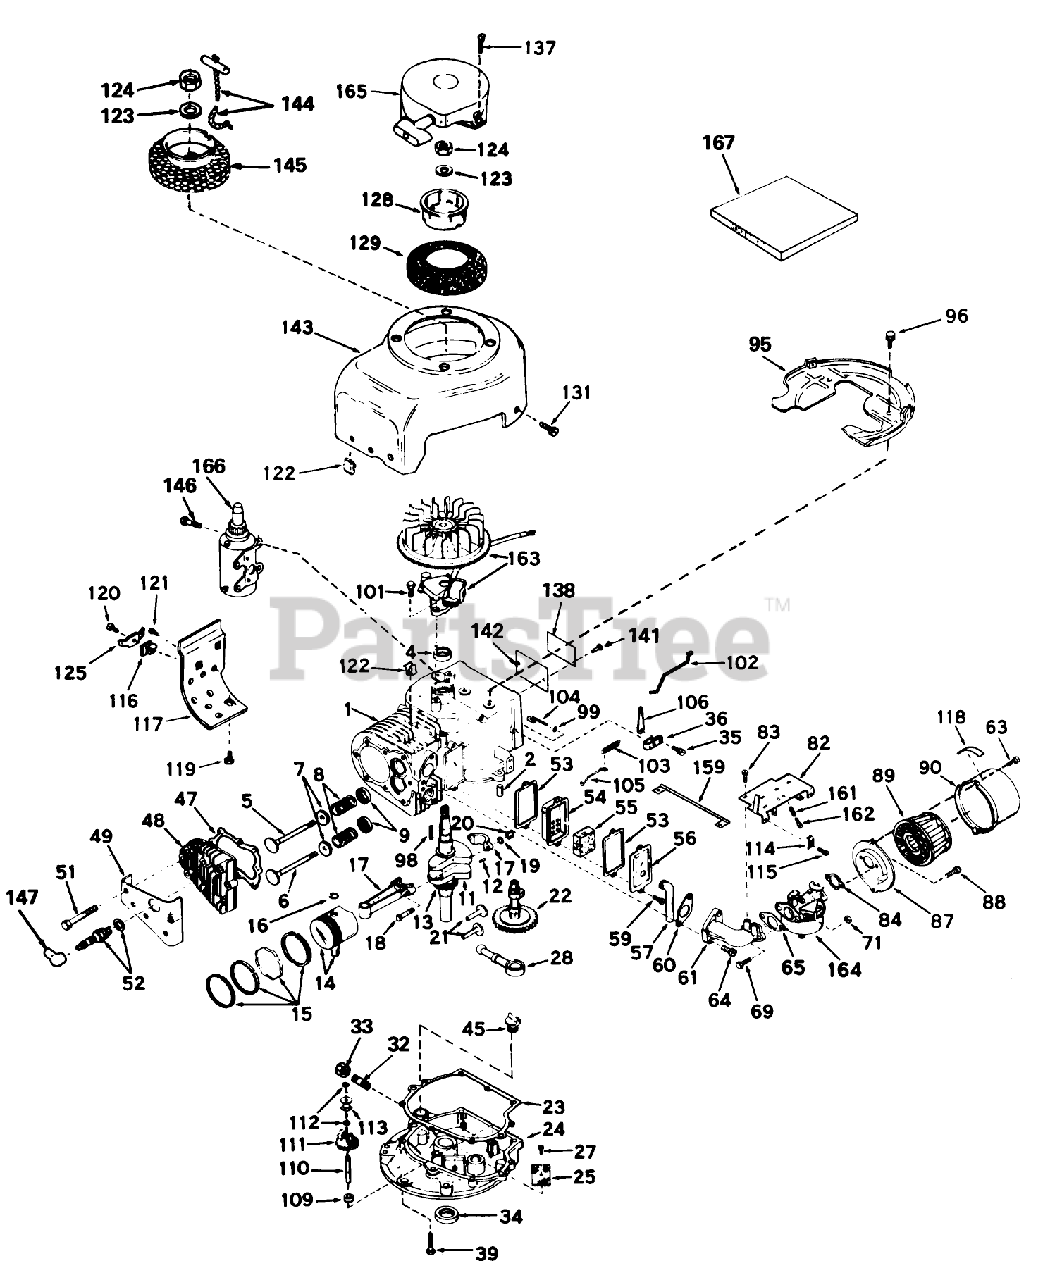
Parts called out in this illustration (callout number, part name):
1	Cylinder Assy. (Incl. Nos. 2 4)
2	Pin-Dowel
4	Seal, Oil
5	Valve, Intake (Std.)(Incl. No. 9)
5	Valve, Intake (1 /32" oversize)(Incl. No. 9)
6	Valve, Exhaust (Standard)(Incl. No. 9)
6	Valve, Exhaust (1/32" oversize)(Incl. No. 9)
7	Cap-Spring, Valve
8	Spring-Valve
9	Keeper-Spring, Valve
11	Crankshaft Assy. (Incl. Nos. 12 13)
12	Pin, Groove
13	Gear-Crankshaft
14	Piston Pin Assy. (Standard)(Incl. 2 of No. 16)
14	Piston Pin Assy. (.010 oversize)(Incl. 2 of No. 16)
14	Piston Pin Assy. (.020 oversize)(Incl. 2 of No. 16)
15	Ring Set, Piston (Std.)
15	Ring Set, Piston (.010 Oversize)
15	Ring Set, Piston (.020 oversize)
17	Rod Assy., Connecting (Incl. Nos. 18, 19 20)
18	Bolt, Connecting Rod
19	Washer
21	Lifter Valve
22	Camshaft (Compression Release)
23	Gasket-Cover, Cylinder
24	Flange Assy., Mounting (Incl. Nos. 25, 27, 29, 34, 45 110)
25	Screen-Oil Filter
27	Screw
28	Pump, Oil
32	Nipple, Pipe
33	Cap-Pipe
34	Seal-Oil
35	Screw
36	Clamp-Lever, Governor
39	Screw (1/4-20 x 1-1/4)
45	Plug-Fill, Oil
47	Gasket-Head, Cylinder
48	CYLINDER HEAD
49	Cover-Head, Cylinder
51	Screw Hex Hd. Cap
52	SPARK PLUG
53	Gasket-Breather
54	Body-Breather
55	Element-Breather
56	Cover-Valve
57	Tube-Breather
59	Screw
60	Gasket-Intake
61	Pipe, Intake
63	Screw
64	Screw (T-30, 5/16-18x1-3/32)
65	Gasket
71	Nut and Lock Washer (1/4-28)
82	Control Assy., Speed (Incl. Nos. 161 162)
83	Screw (10-24 x 9/16)
84	Gasket
87	Bracket
88	Screw (10-32 x 1/2)
89	Element
90	Body
95	Baffle Blower Housing
96	Screw (1/4-20x19/32)
98	Key, Flywheel
99	Washer-Flat
101	Screw
102	Link Governor
103	Spring Governor
104	Rod, Governor (Incl. Nos. 146)
105	Link Governor Spring
106	Lever-Governor
109	Spacer
110	Shaft, Governor
111	Governor Gear ASM
112	Ring-Retaining
113	Spool-Governor
114	Conduit
115	Screw (10-32 x 3/8)
116	Grommet
117	Emnsion, Blower Housing
118	Decal
119	Screw
120	Screw
121	Screw
122	51004 GIL ROTARY TI
123	Washer
125	Terminal, Ground
128	Cup-Starter
129	Screen, Air
131	Screw, Hex Hd.
137	Screw
138	480B GIL SNWTHWR O/
141	DRIVE STUD
142	IDENTIFICATION PLATE
143	Housing, Blower
144	Rope Assy., Starter
145	Hub Screen, Rope Starter
146	Screw
147	Cover-Spark Plug
159	Wire, Ground
161	Spring-Compression
162	Screw
163	Magneto
164	Carburetor
165	Starter, Rewind
166	Motor, Starter
167	Gasket Set (Incl. items marked*)
